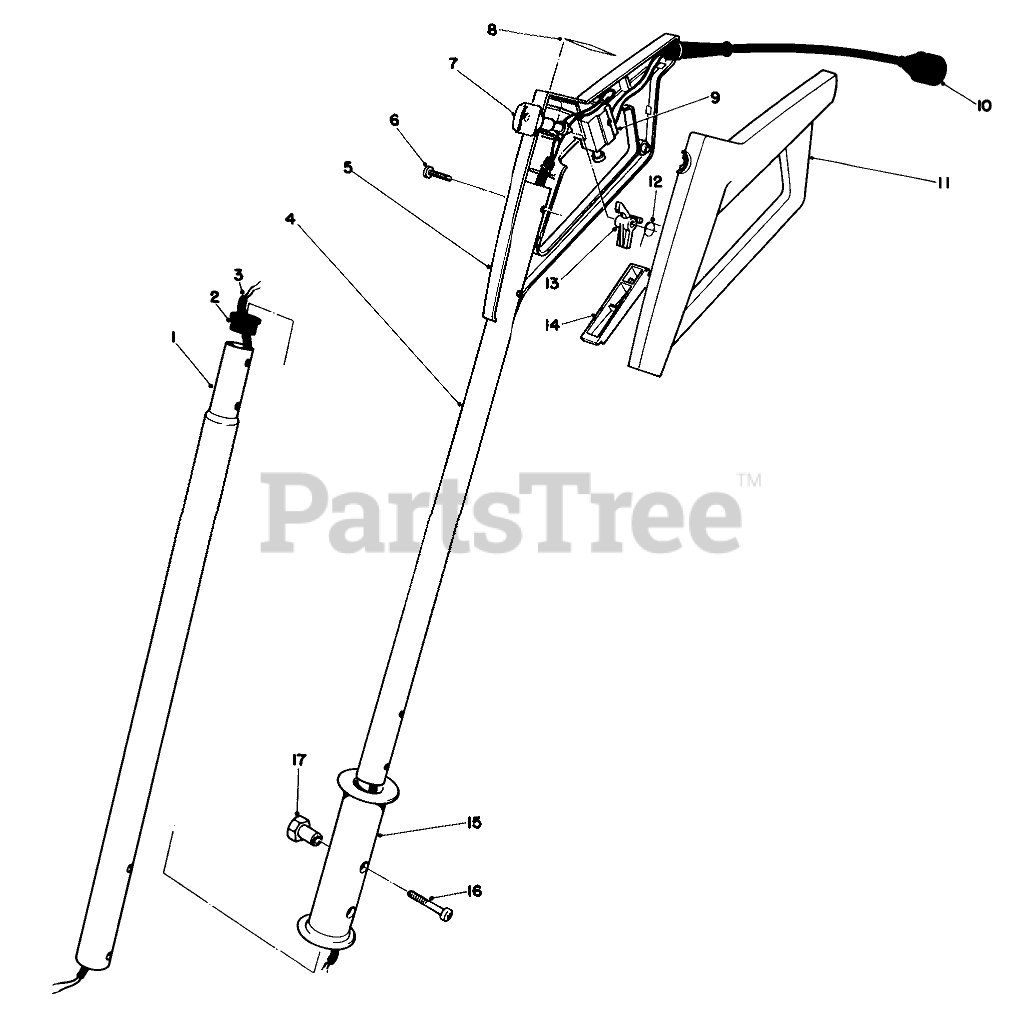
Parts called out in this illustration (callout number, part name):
1	LOWER HANDLE TUBE
2	BUSHING
3	WIRE HARNESS
4	UPPER HANDLE TUBE
5	RT HALF CONT GRIP
6	SCREW-PPH
8	UL GRIP DECAL
9	SWITCH-STARTER
10	Cord Supply
11	LEFT HALF CONT GRIP
12	TORSION SPRING
13	LOCKOUT
14	SWITCH BAR
15	Handle Grip
16	SPEC PAN HD SCREW
17	SPECIAL HEX NUT
